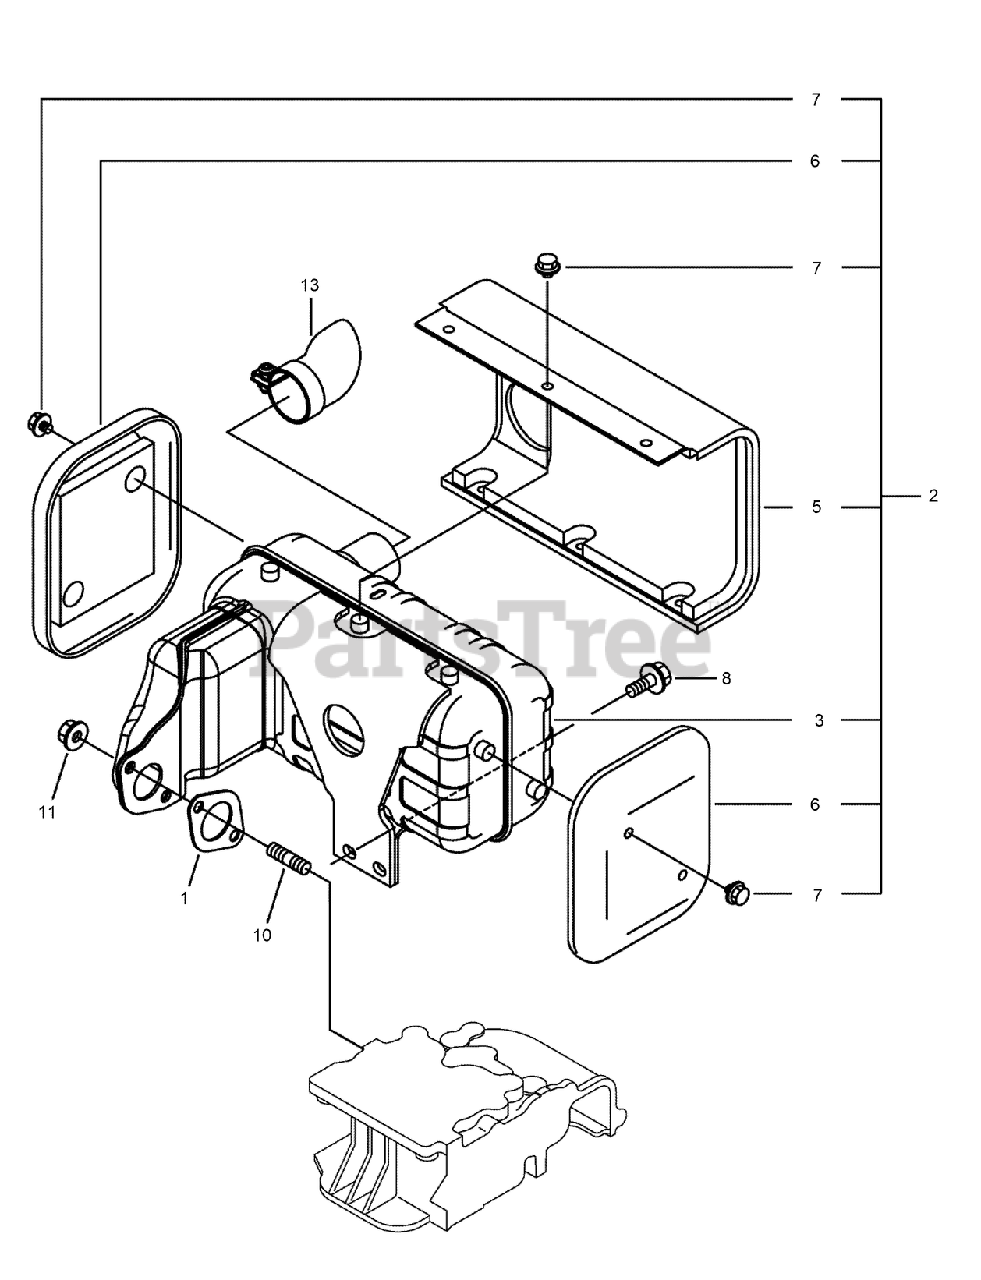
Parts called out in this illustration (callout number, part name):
1	GASKET-MUFFLER
2	MUFFLER ASM
3	MUFFLER
5	COVER-MUFFLER A
6	COVER-MUFFLER B
10	STUD-BOLT
13	EXHAUST DEFLECTOR ASM
